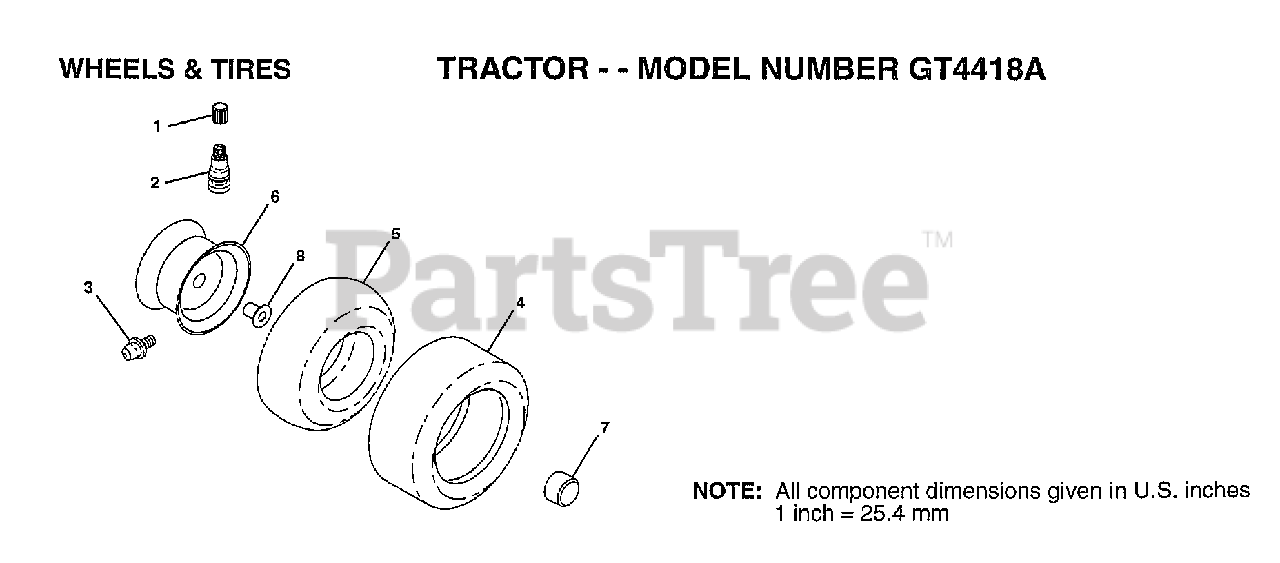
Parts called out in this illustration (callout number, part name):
1	VALVE CAP
2	VALVE STEM LT
3	FITTING LT
4	TIRE.R.23X9.5-12
5	TUBE.5.3/4.5/6
5	TUBE.23X8/10-12
6	"RIM ASM FRT 8"""
6	"RIM.ASM.REAR.12"""
7	HUB CAP
8	"FLANGE, BEARING"
